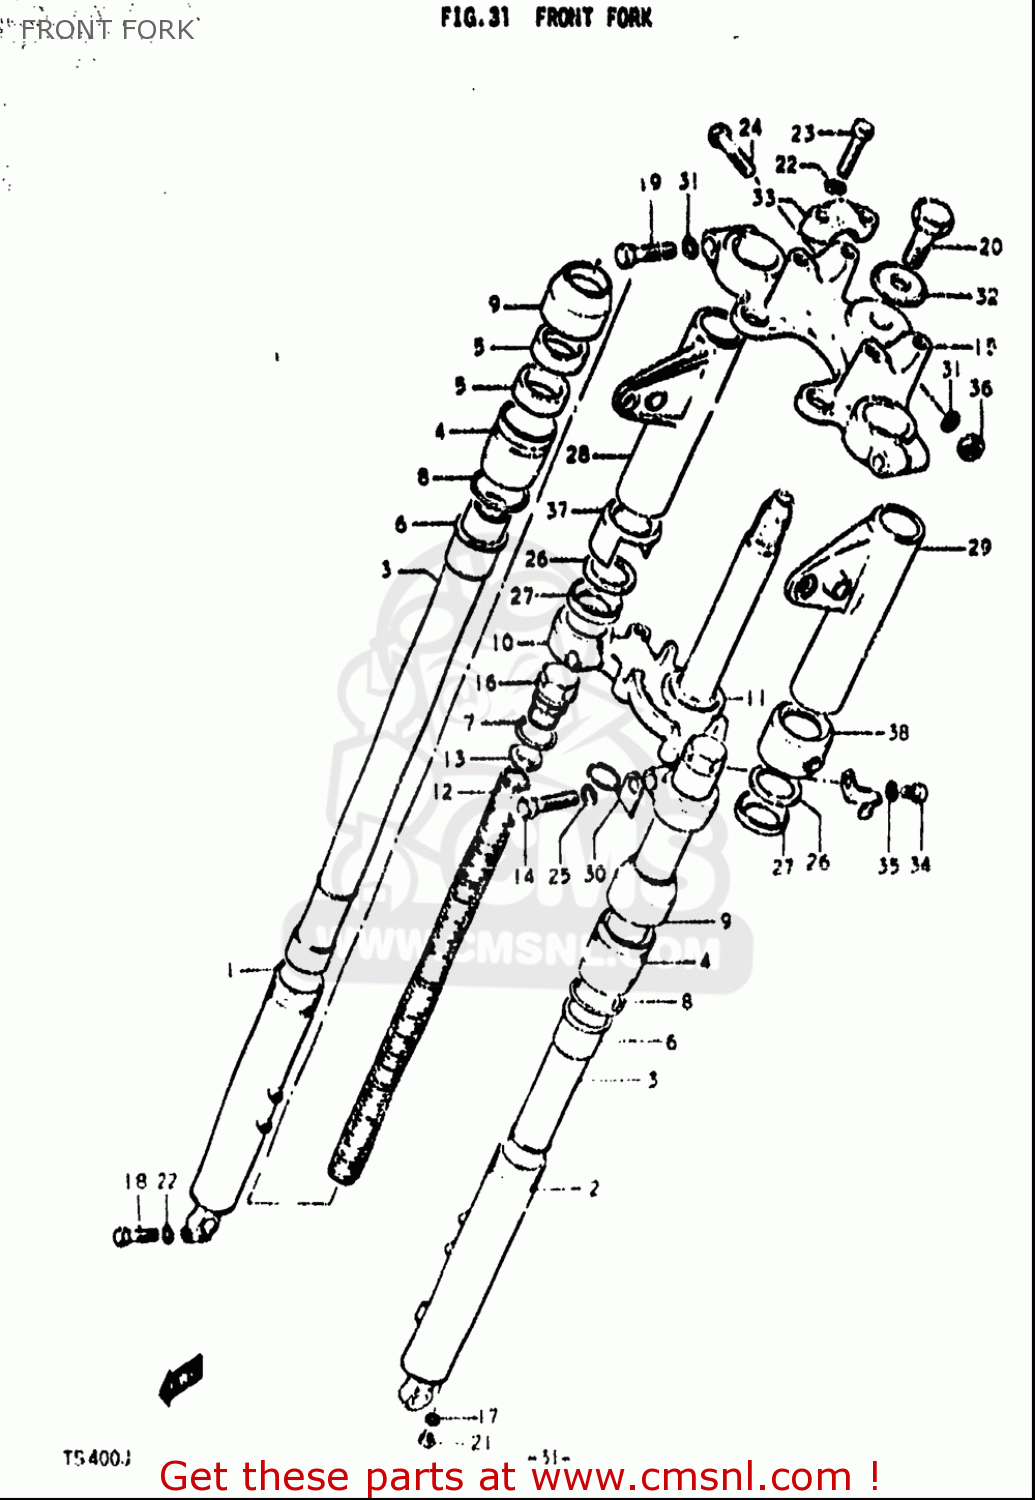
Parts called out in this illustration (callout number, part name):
4	NUT,FORK OUTER TUBE
5	SEAL,OIL
7	O RING
11	RACE,STEERING OUTER LWR
17	GASKET,DRAIN,PLUG (NAS)
18	BOLT
19	BOLT,FORK INNER TUBE F
20	BOLT,FR FORK(10X33)
22	WASHER,LOCK
23	BOLT
25	WASHER,LOCK
26	CUSHION,HEADLAMP BRACKET
27	GUIDE, COVER
30	CLIP
31	WASHER,LOCK
32	WASHER
33	HOLDER,HANDLEBAR
34	SCREW
35	WASHER,LOCK
36	NUT
